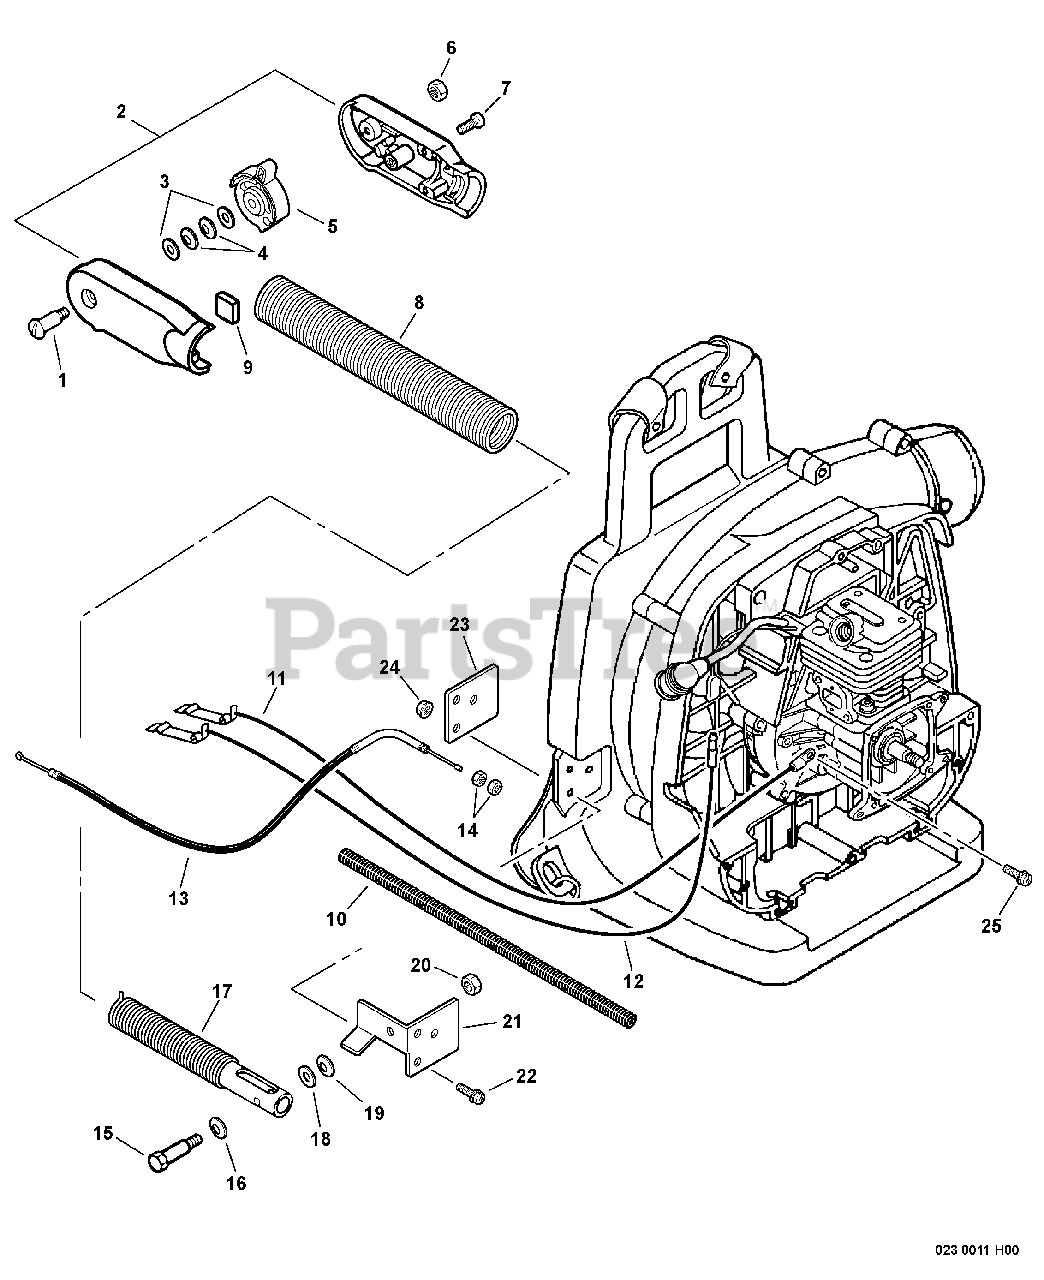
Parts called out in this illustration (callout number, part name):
1	SCREW - 4
2	CONTROL HANDLE ASSY
3	WASHER - 6
4	WASHER - SPRING
5	LEVER, THROTTLE CONTROL
6	LOCKNUT - 4
7	SCREW - 5X20
9	PAD, FOAM
10	TUBE, PROTECTIVE - CORRUGATED
11	LEAD - GROUND
12	LEAD - IGNITION
13	CABLE, THROTTLE
15	BOLT - 6
16	WASHER - SPRING
17	TUBE, SPRING
18	WASHER - 8
19	WASHER - 8
20	LOCKNUT - 1/4"
21	BRACKET
22	SCREW - 5X16
24	NUT - 5 -- FLANGE
25	SCREW - 5X10
